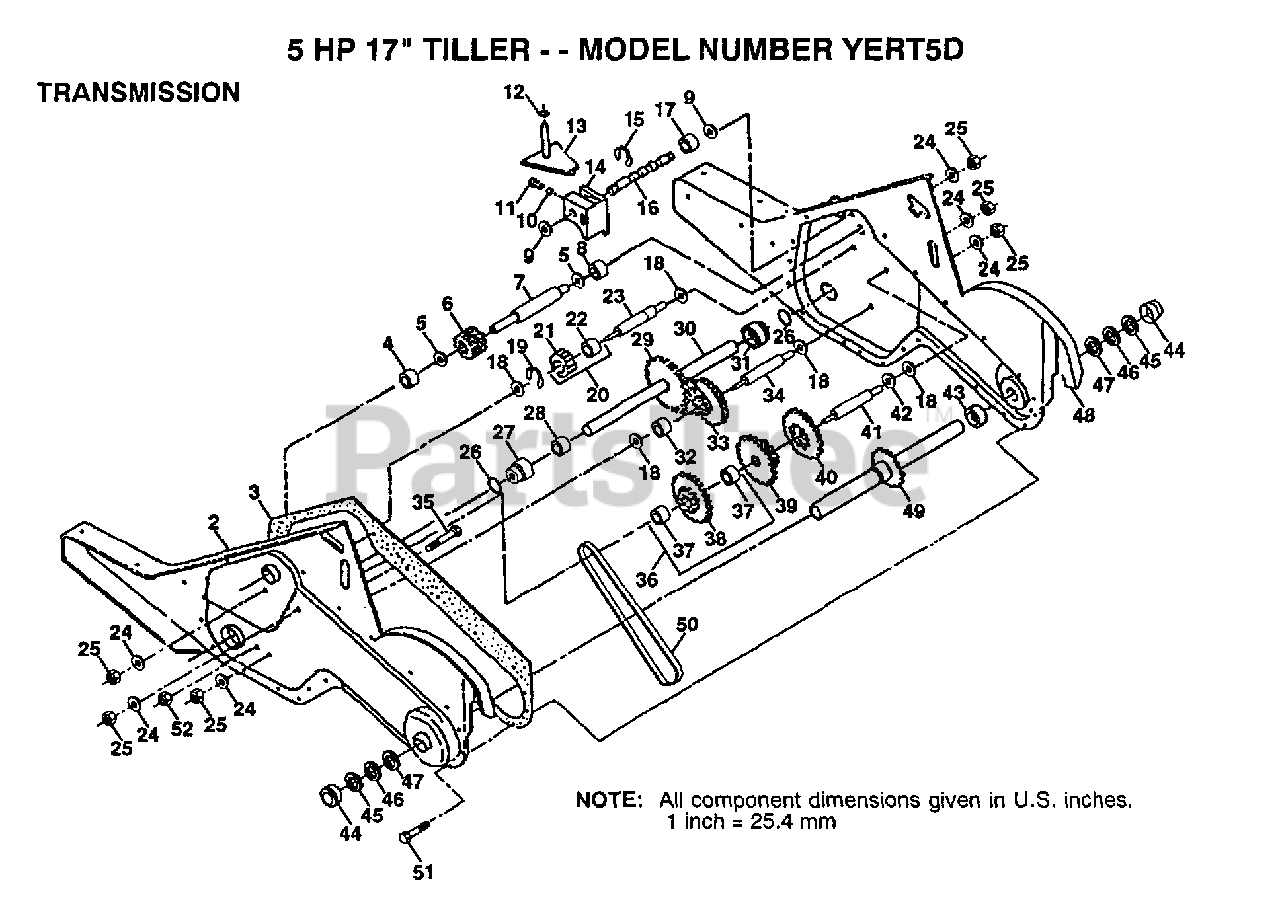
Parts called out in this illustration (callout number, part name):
3	GASKET TI
4	NEEDLE BRNG LT
5	"T, BEARING"
6	PINION-INPUT CRT
7	SHAFT-INPUT CRT
8	"TI, BEARING"
9	WASHER SEAL CRT
11	SPRING-SHIFT CRT
12	SPRING-SHIFT CRT
13	ARM ASSY CRT
14	SHIFT FORK TI
15	KLIP RING
17	SPACER, SPLIT
18	WASHER
19	KLIP RING
20	GEAR ASSY REVERSE IDLER
21	GEAR REVERSE IDLER
22	NEEDLE BEARING TI
24	LOCKWASHER
25	NUT.ASF.HEX.7/16
27	BEARING SHAFT GROUND DRIVE
30	GROUND SHAFT ASSY
31	BEARING SHAFT GROUND DRIVE
33	SPROCKET AND GEAR ASSY
34	SHAFT REDUCTION
35	SCRW WHIZ LOK CRT
36	SPROCKET ASM.
37	BEARING
39	GEAR TI
40	GEAR TI
41	REDUCTION SHFT TI
42	BRNG RACE
43	SPACER TI
44	CUP.FORMED.
45	RING SPIRAL CRT
49	TINE SHAFT
50	CHAIN.50 LINK TI
51	SCREW CRT
52	NUT.HEX.5/16-18
